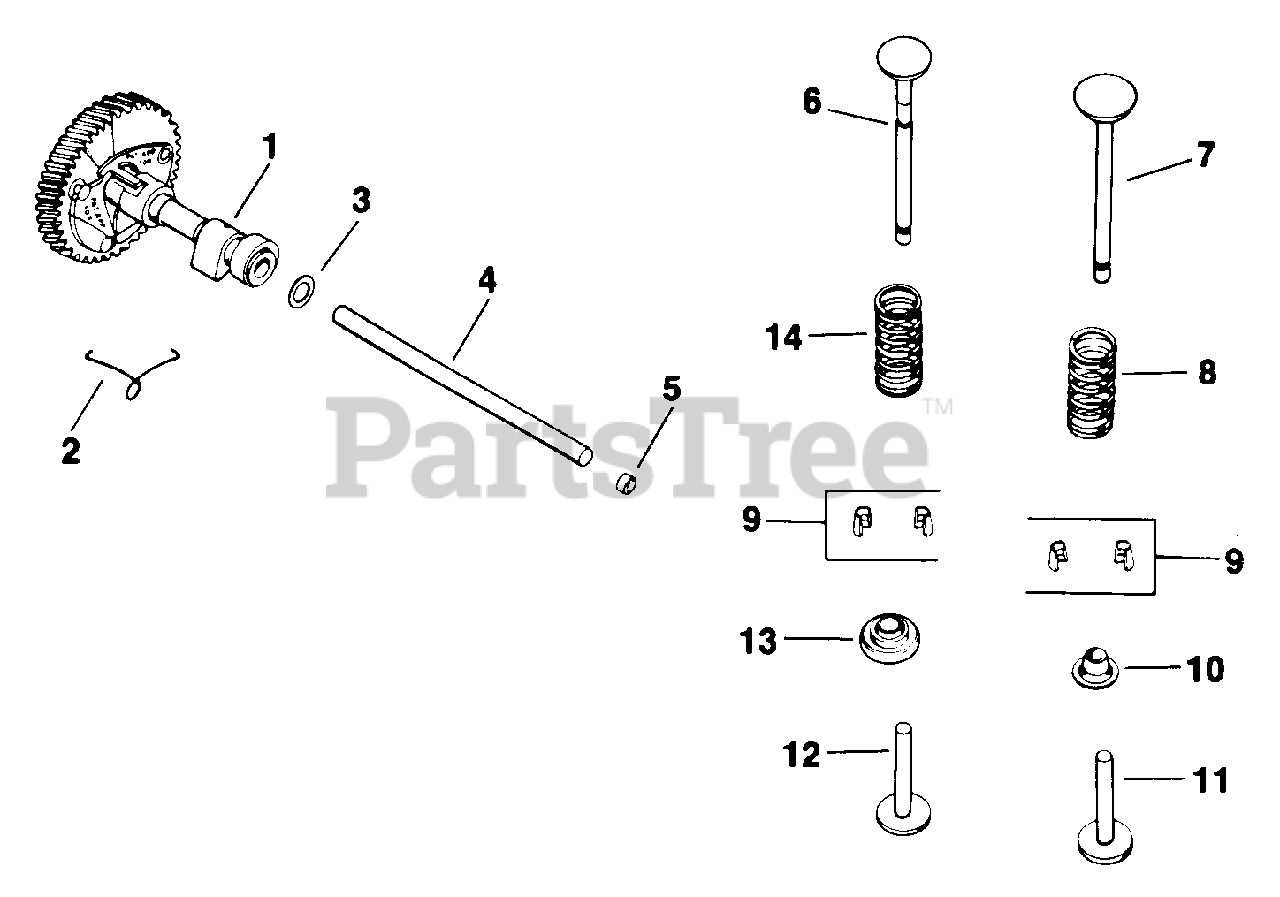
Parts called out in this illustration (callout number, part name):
1	CAMSHAFT - DISCONTINUED
2	SPRING, ACTUATING-DISCONTINUED
4	PIN - DISCONTINUED
5	PLUG, CUP
6	VALVE - DISCONTINUED
7	VALVE - DISCONTINUED
8	SPRING - DISCONTINUED
9	KIT, RETAINER
10	RETAINER, VALVE SPRING
11	TAPPET - DISCONTINUED
14	SPRING - DISCONTINUED
